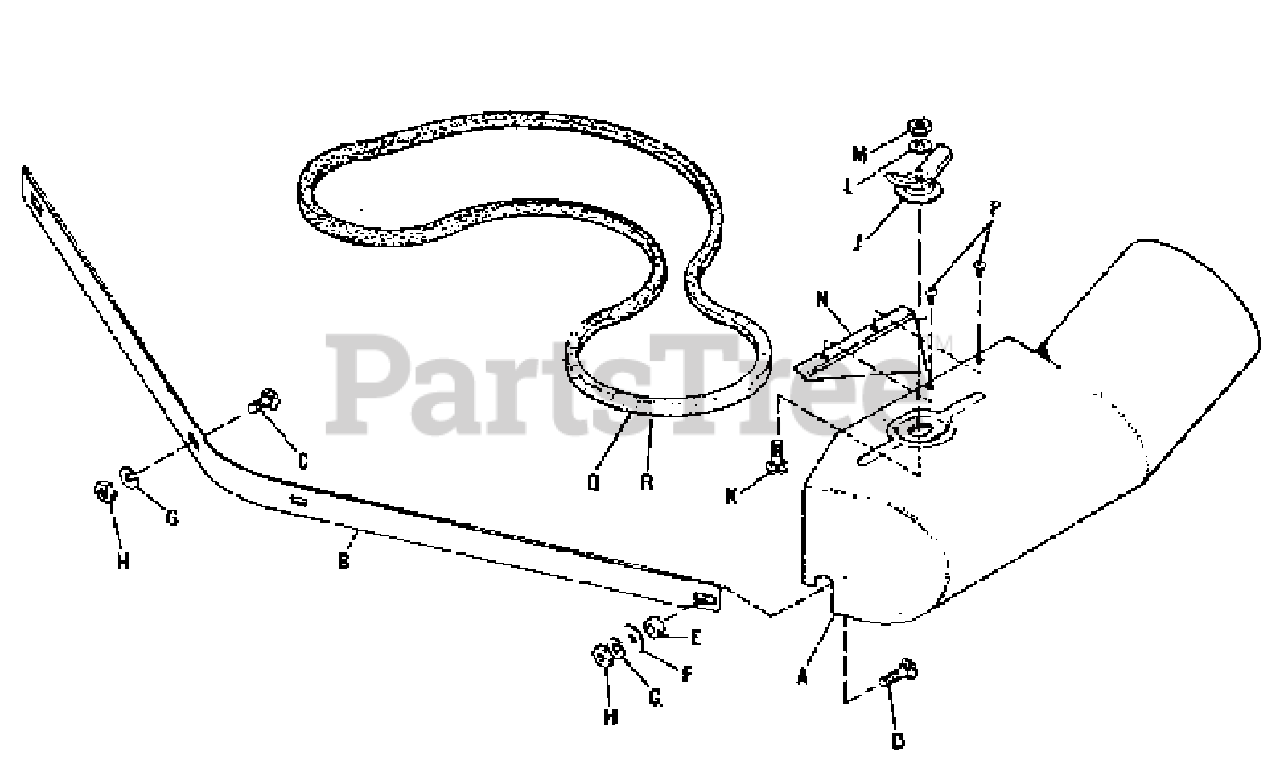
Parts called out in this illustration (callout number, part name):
A	COLLECTOR SIDE HOUSING ASSEMBLY
B	FRONT BAFFLE
C	CARRIAGE BOLT, 3/8" - 16 x 1" LG
D	CARRIAGE BOLT, 3/8" - 16 x 1-1/4" LG
G	LOCK WASHER, 3/8"
H	NUT, Hex, Full, 3/8" - 16
J	NUT ASSEMBLY
K	CARRIAGE BOLT, 3/8" - 16 x 1" LG
L	LOCK WASHER, 3/8"
M	NUT, Hex, Full, 3/8" - 16
P	SCREW, Self Tapping, No, 10-24 x 1/2" LG
Q	BELT, "V"
R	BELT, "V"
